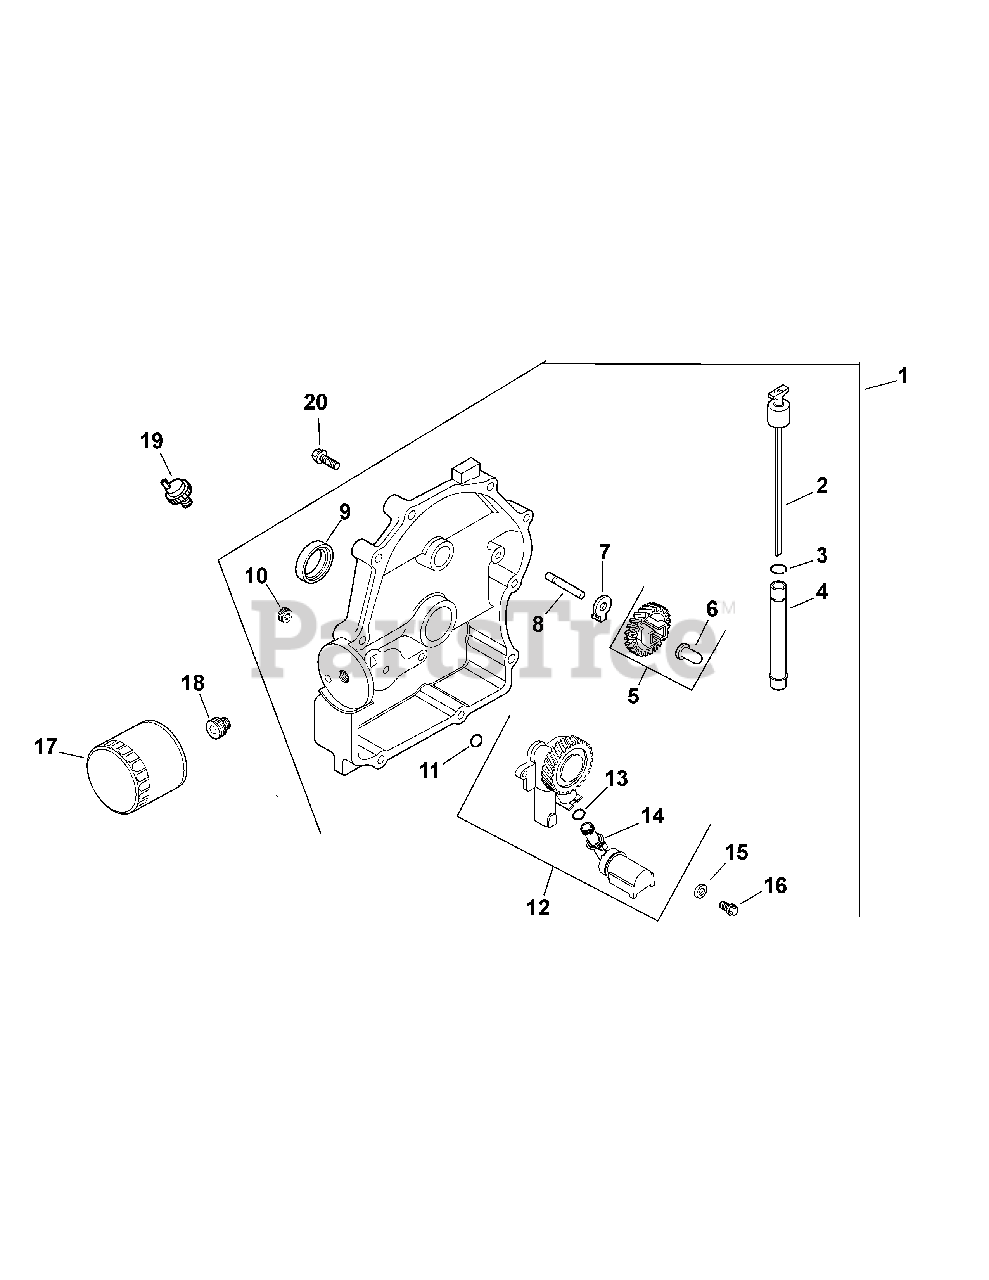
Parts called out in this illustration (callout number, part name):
1	Kit, Closure Plate Ass’y (Inc. 2-15)
4	Kit, Oil Fill Tube
5	Kit, Governor Gear w/ Pin (Inc. 6)
6	Pin, Governor Regulating
8	Shaft, Governor Gear
10	Plug, Pipe CTSK 1/8"
12	Kit, Oil Pump Assembly (Inc. 13, 14)
13	O-Ring, Oil Pick-Up
14	Pick-Up, Oil
15	Washer, Flat 6MM
16	Screw, Flg Thd Frm M6X1.0X25
18	Nipple, Oil Filter
19	Switch, Oil Pressure
20	Screw, Flg M8x1.25x45
